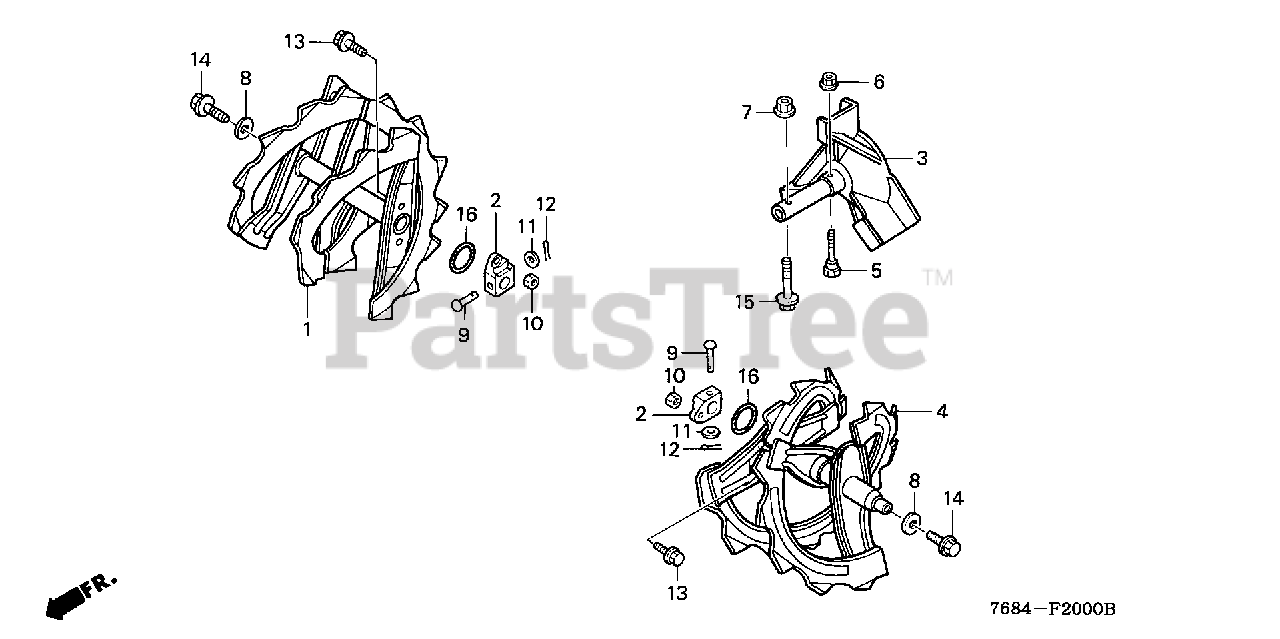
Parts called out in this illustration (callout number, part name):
2	BOSS, LOCK BOLT
5	BOLT, LOCK
6	NUT, SELF-LOCK (6MM)
7	NUT, FLANGE (M8X1.25) (SELF-LOCK)
8	WASHER (23X8.3X3.2)
9	PIN (7X40)
10	NUT, SELF-LOCK (6MM)
11	WASHER, PLAIN (7MM)
12	PIN, SPLIT (3.0X25)
12	PIN, SPLIT (3.0X45)
13	BOLT, HEX. (6X16)
14	BOLT, FLANGE (8X16)
15	BOLT, FLANGE (8X35)
16	O-RING (19.8X1.9) (ARAI)
NI	AUGER SKID KIT, COMMERCIAL
